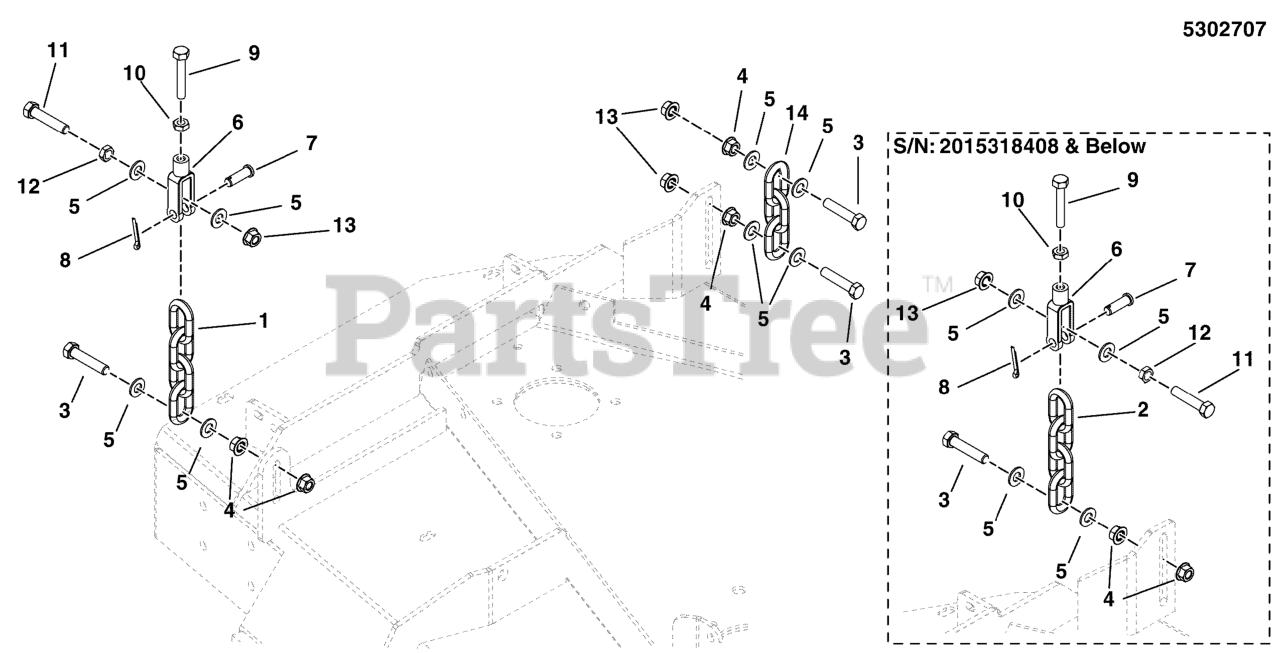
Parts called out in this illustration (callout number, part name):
2	CHAIN, 5/16" GD30, 4 LINKS
3	BOLT, 3/8-16 X 1-3/4" GD5 CZ
4	NUT, 3/8-16 HEX SERRATED FLANGE
5	WASHER, 3/8 SAE
6	CLEVIS, 5/16-18, 3/8 PIN HOLE
7	PIN, CLEVIS, 3/8 X 1-1/8, YZ
8	PIN, COTTER, 1/8 X 1-1/4
9	BOLT, 5/16-18 X 2 GD5 TFL
10	NUT, 5/16-18 HEX JAM
11	BOLT, 3/8-16 X 2, GD5, CZ
12	NUT, 3/8-16 HEX JAM
13	NUT, 3/8-16 HEX NYLOCK FLANGE
14	CHAIN, 5/16" GD30, 3 LINKS
